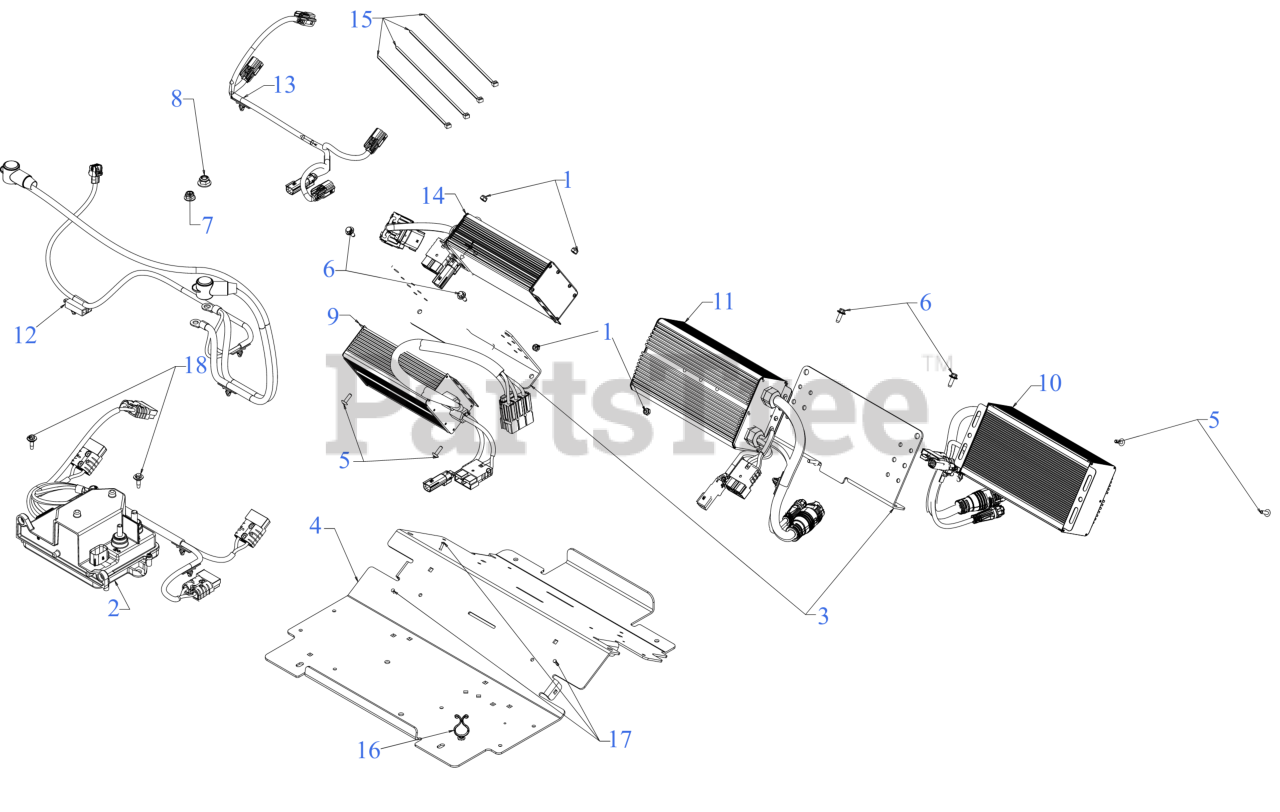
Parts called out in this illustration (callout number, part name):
2	PDM HOUSING (4FUSE)
3	CONTROLLER BRACKET
4	CONTROLLER PLATE
5	SCREW #10-24 x .62
6	SCREW M6-1 x .625
7	FLANGE LOCK NUT 5/16-18
9	MOTOR CONTROL (R TRAC)
10	MOTOR CONTROL (L DECK)
11	MOTOR CONTROL (R DECK)
14	MOTOR CONTROL (L TRAC)
15	TIE CABLE 8.5 LG
16	TWIST LOCK CLIP
17	PANEL RATCHET CLIP .125 x .750
18	SHOULDER SCREW M6-1 .368 X.115
